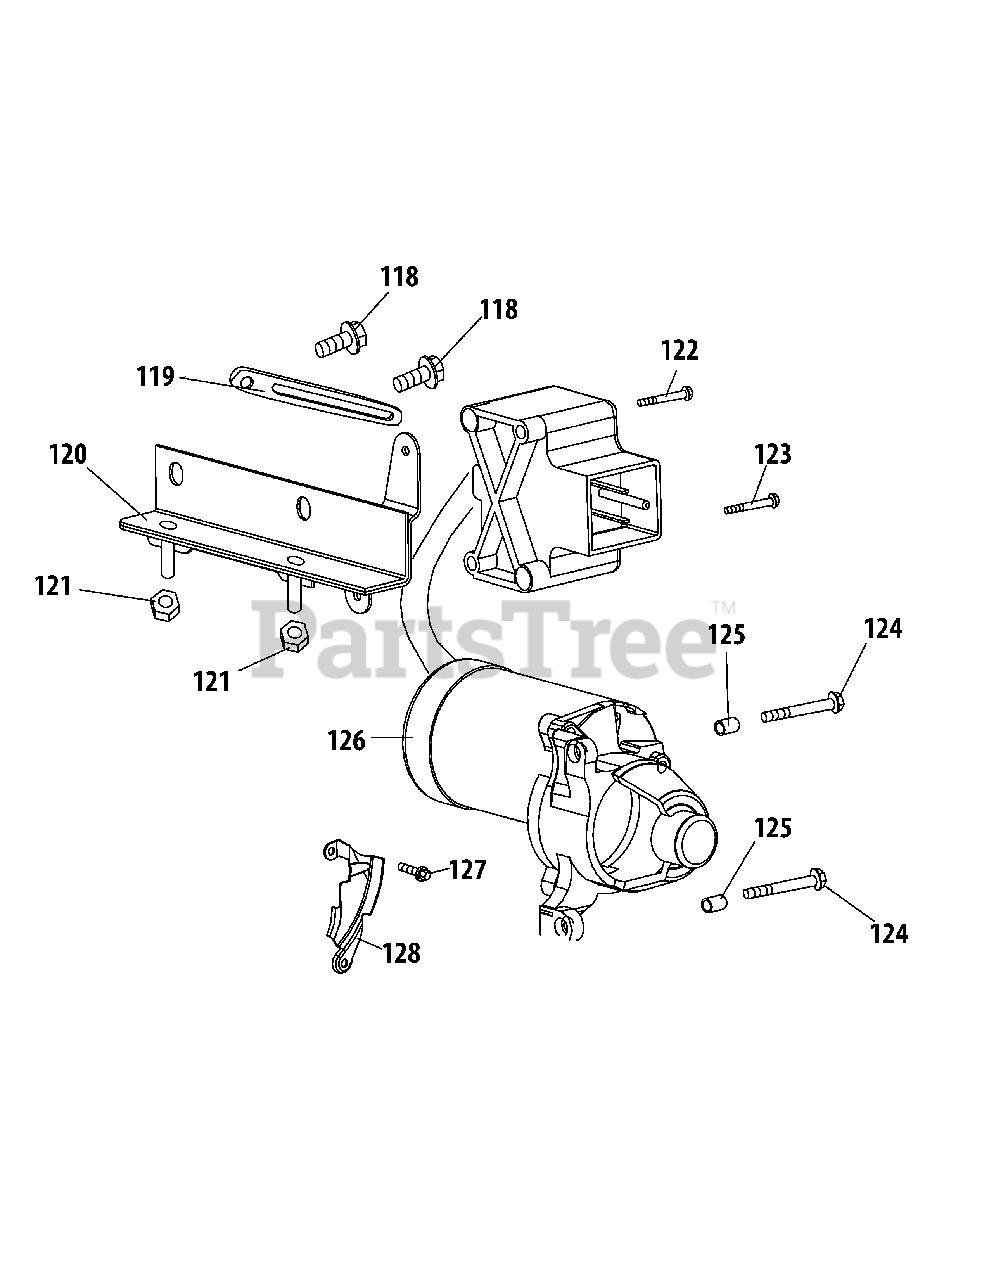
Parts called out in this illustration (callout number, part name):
118	Bolt - Flange M6
119	Flexible Clamp
120	Bracket - Switch Housing Mount
122	Screw M4 X 55
123	Screw - M4 X 60
124	Bolt-M6 X 32
125	Pin - Dowel
126	Electric Starter
127	Bolt - M6 X 12 Zin
128	Shield - Blower Housing
